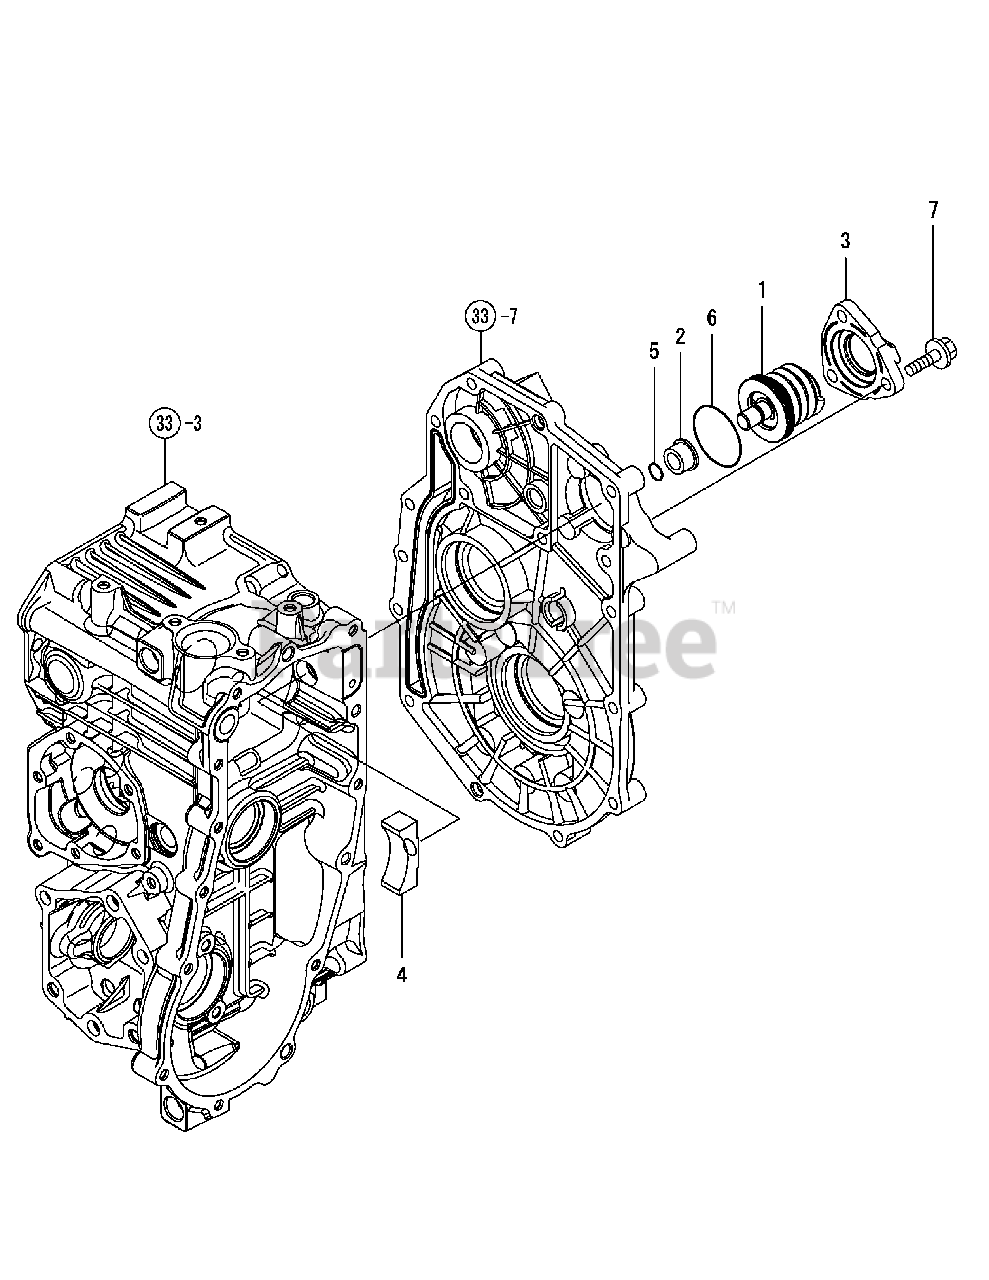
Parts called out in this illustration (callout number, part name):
1	BRAKE KIT, PTO
2	COLLAR, BRAKE PIN
3	COVER, PTO BRAKE
4	SHOE, PTO BRAKE
5	O-RING 1A P-10.0
6	PACKING 1A 2045
7	BOLT M 8X 25 PLATED
